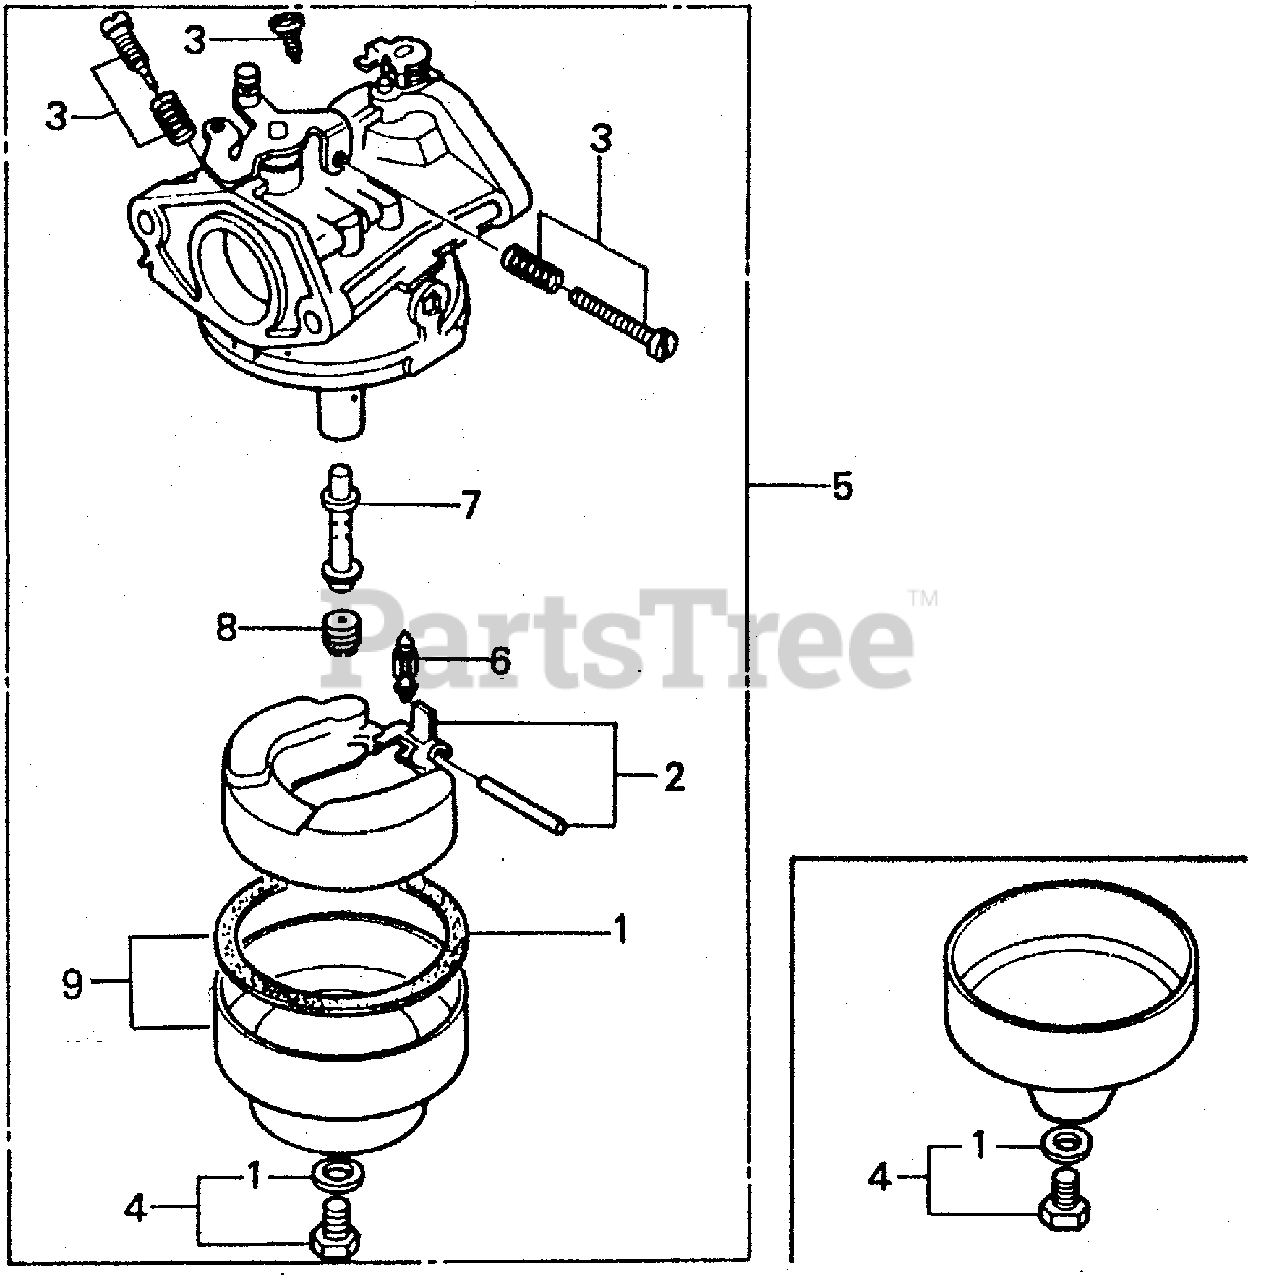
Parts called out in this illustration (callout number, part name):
1	GASKET SET
3	SCREW SET A
4	SCREW SET B
5	CARBURETOR ASSY. (BB27A E)
6	VALVE, FLOAT
7	NOZZLE, MAIN (NOT AVAILABLE)
8	JET, MAIN (#65)
9	CHAMBER SET, FLOAT
